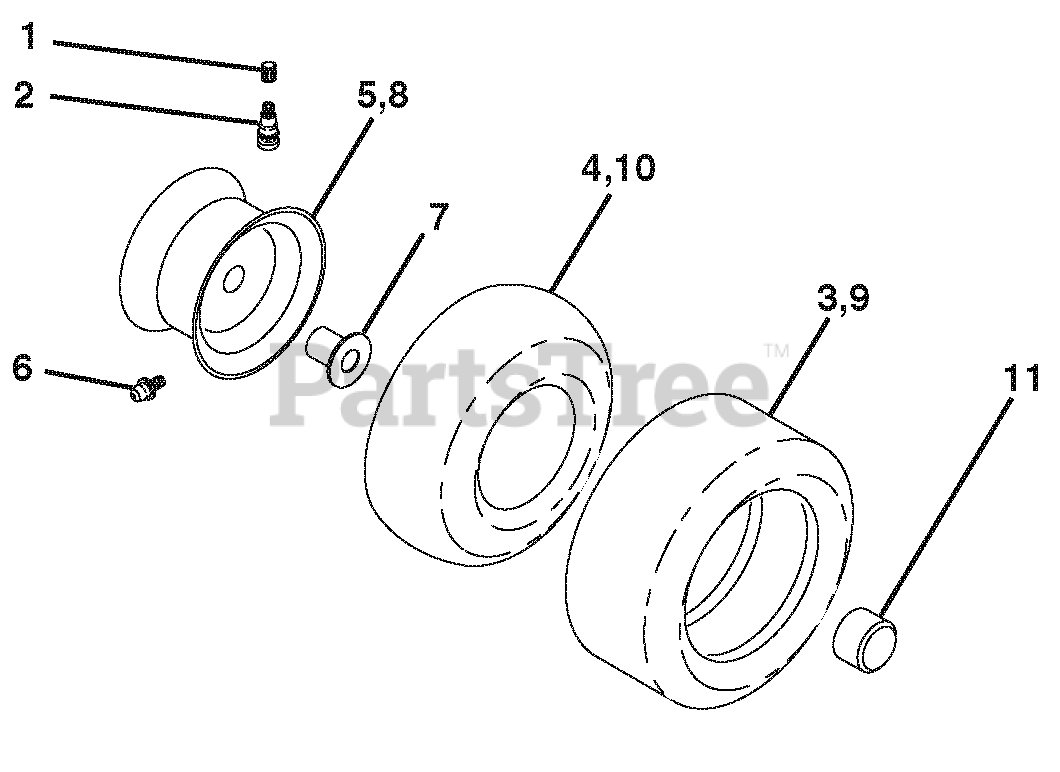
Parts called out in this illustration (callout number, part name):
1	CAP.VALVE.TIRE
2	STEM.VALVE
3	TIRE.F.TS.15 X 6.0 - 6.SERVICE
4	TUBE.INNER.FRONT.#35060
5	RIM ASSEMBLY 6" FRONT
6	FITTING, GREASE
7	BEARING FLANGE
8	RIM ASSEMBLY 8" REAR
9	TIRE.R.TS.20 X 8-8.C.SERVICE
10	TUBE, REAR
11	CAP AXLE (FRONT WHEEL ONLY)
